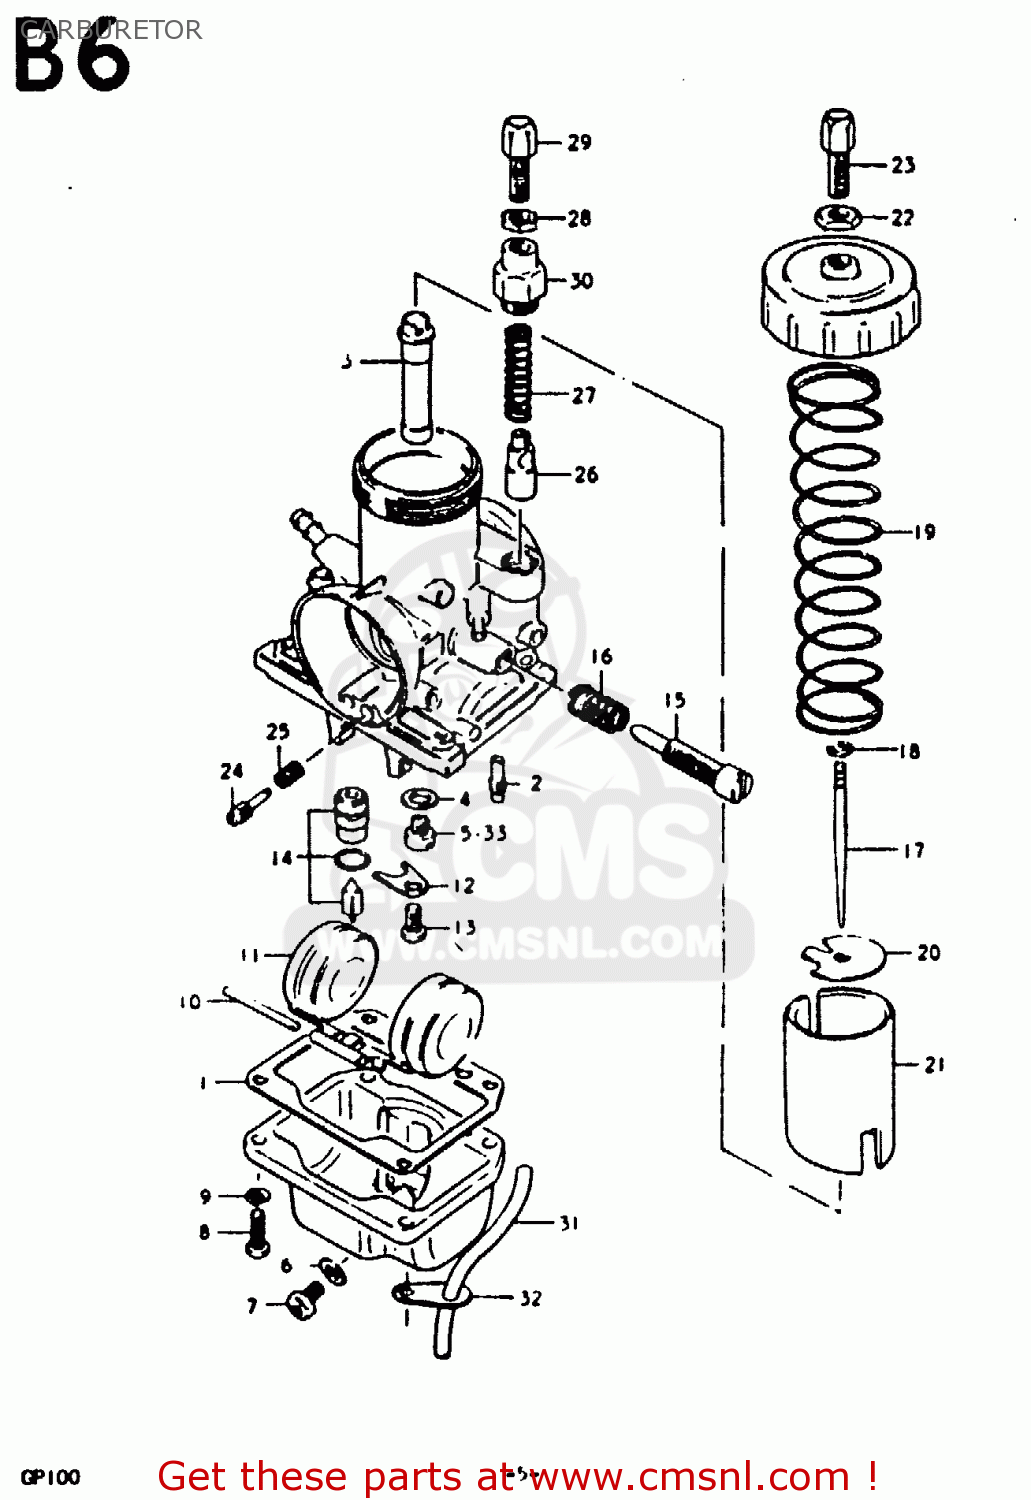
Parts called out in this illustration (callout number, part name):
1	GASKET,FLOAT CAHMBER (NAS)
2	JET
3	JET, NEEDLE (0-8)
4	WASHER
5	JET
6	GASKET,DRAIN,PLUG (NAS)
7	PLUG
8	SCREW
9	LOCK WASHER
10	PIN,FLOAT
11	FLOAT
12	PLATE
13	SCREW
14	VALVE ASSY, NEEDLE
15	ADJUSTER
16	SPRING,THROTTLE SCREW
17	NEEDLE,JET
18	E-RING
19	SPRING, THROTTLE VALVE
20	PLATE
21	VALVE,THROTTLE
22	NUT
23	ADJUSTER,CABLE
24	SCREW,PILOT AIR
25	SPRING
26	PLUNGER,STARTER
27	SPRING
28	NUT
29	ADJUSTER,CABLE
30	CAP
31	HOSE
32	PLATE
33	JET
